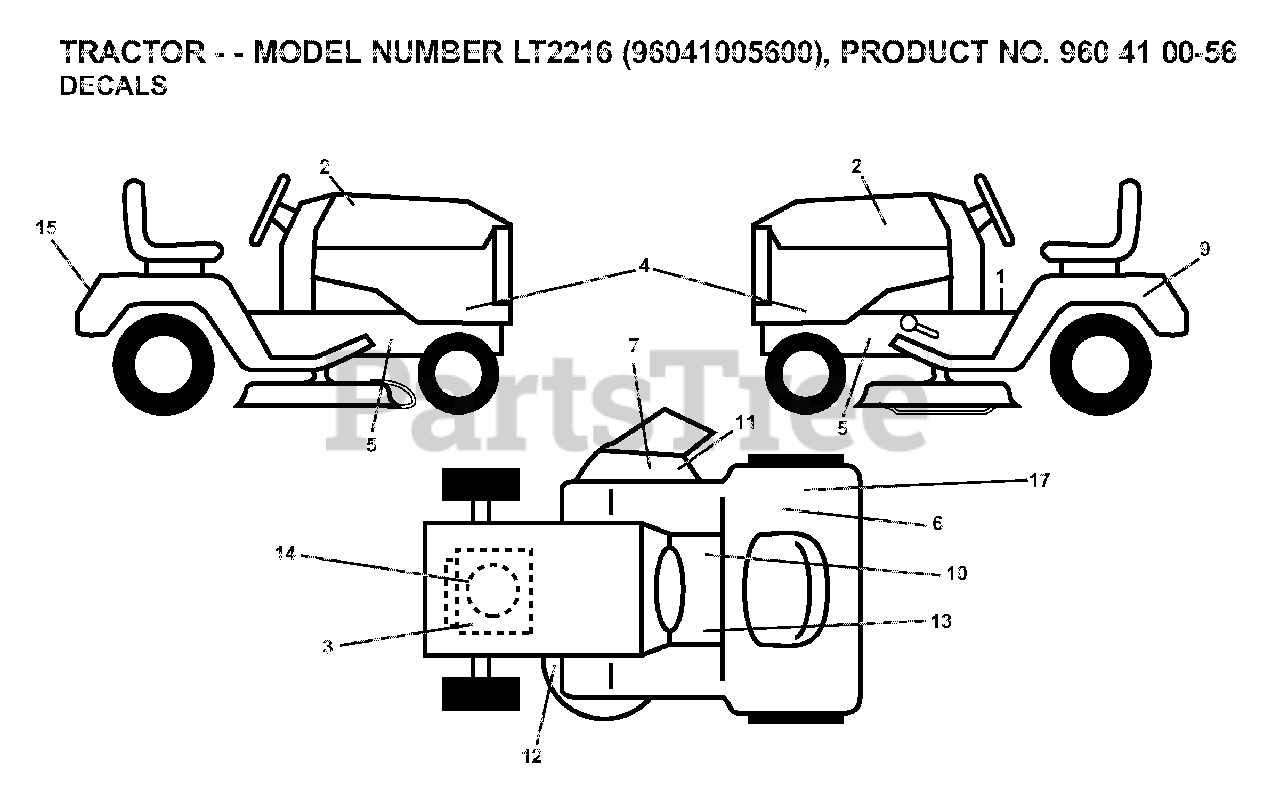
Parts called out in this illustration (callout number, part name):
6	DECAL.80 DBA.AUSTRALIA
7	DECAL.INTERNATIONL.CUTFINGER
9	DECAL BTRY SYMBOLS
10	DECAL PARK BRAKE
11	DECAL, DEFLECT WARNING
12	DECAL.V-BELT.SCHEMATIC.36/38/9
